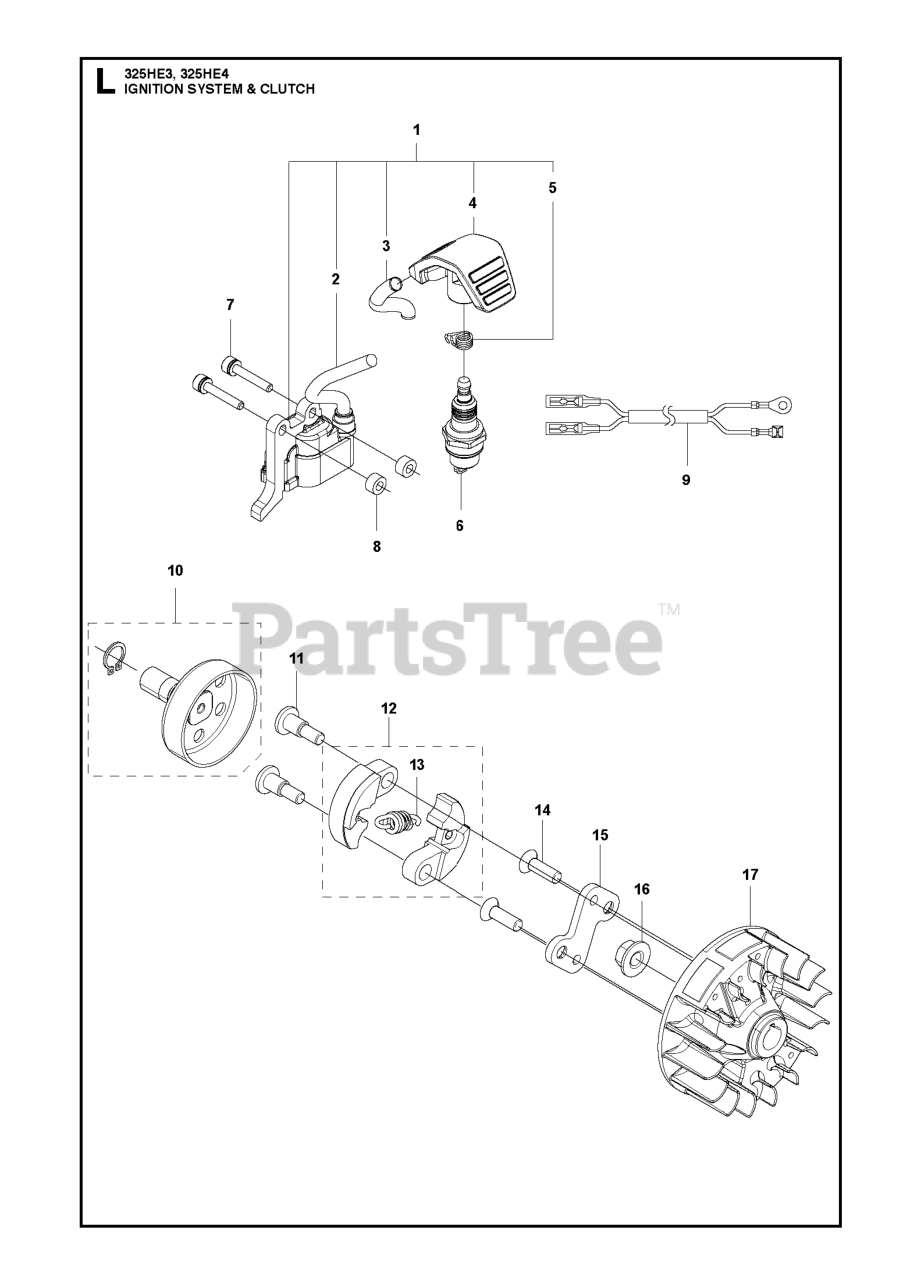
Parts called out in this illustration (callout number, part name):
1	IGNITION COIL ASSY
2	IGNITION CABLE
4	SPARK PLUG CAP
6	SPARK PLUG NGK BPMR-8Y
7	BOLT M4 X 25
9	SHORT CIRCUIT CABLE
10	KIT CLUTCH DRUM ASSY
11	SCREW CLUTCH
13	CLUTCH SPRING
15	CLUTCH HUB
16	NUT
